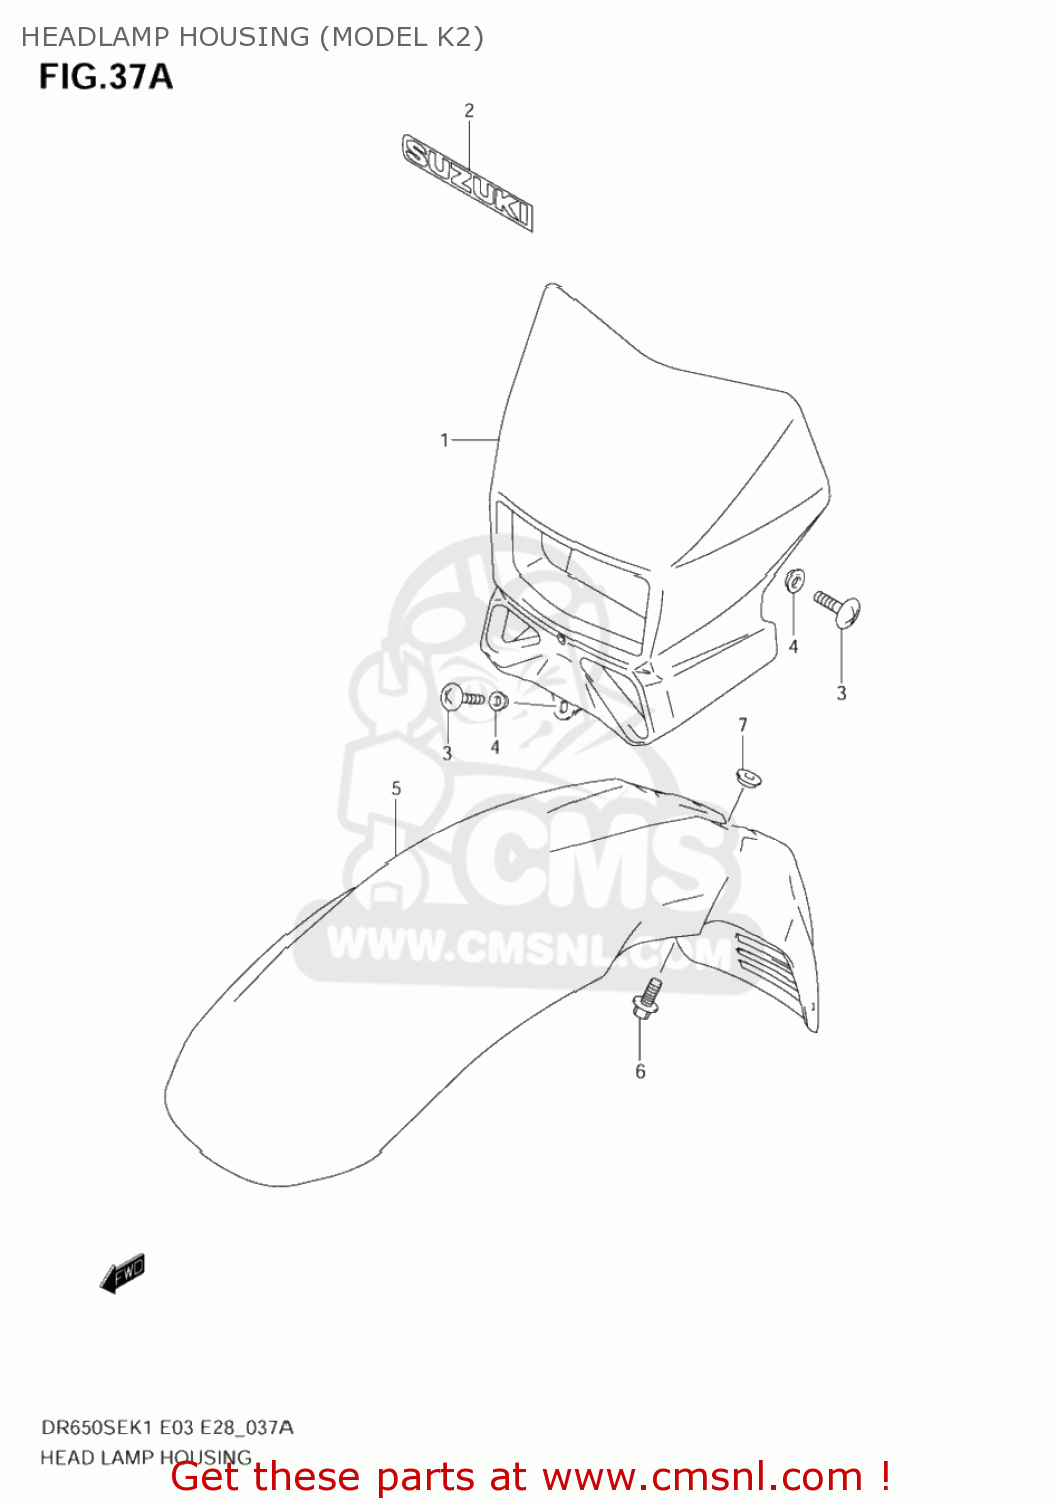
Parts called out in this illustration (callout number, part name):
1	COVER,HEADLAMP
2	EMBLEM,SUZUKI
3	SCREW 6X12
4	WASHER
5	FENDER,FR
6	BOLT(6X16)
7	WASHER
